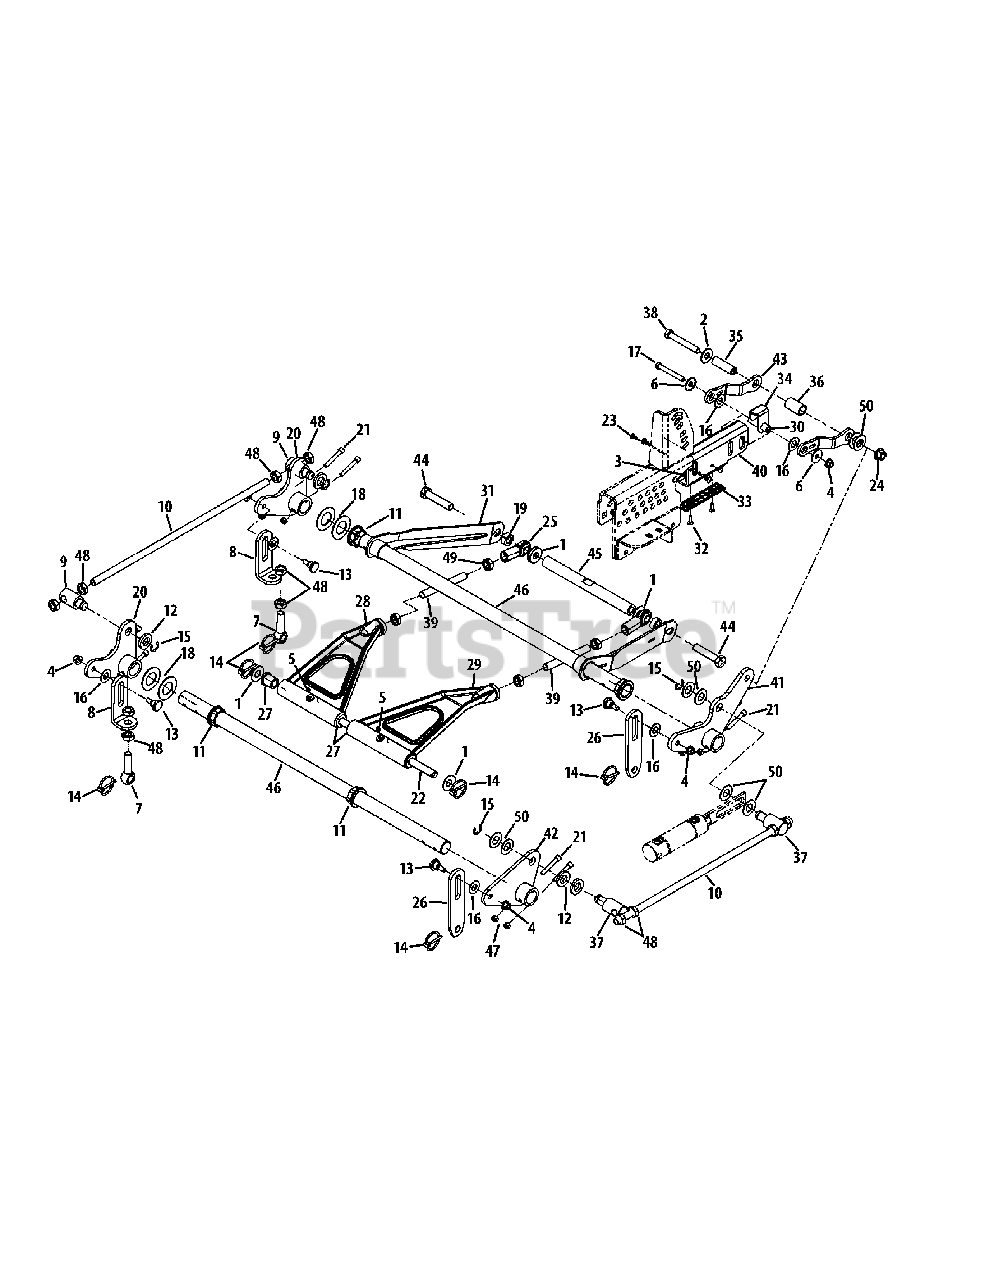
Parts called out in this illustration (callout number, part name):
1	Washer, .655 x 1.5 x .055
2	Washer, .563 x 1.38 x .109
3	Nut, 1/4-20
4	Flg. Cnter. Lock Nut, 3/8-16 (60" Deck)
5	Grease Fitting, 1/4-28
6	Washer, .411 x 1.25 x 1.00
7	Eye Bolt, 5/8-16 x 2.63
8	Eye Bolt Link, 5/8
9	Lift Ferrule
10	Lift Connecting Rod
11	Hex Flange Bearing
12	Spacer, .812 x 1.47 x .218
13	Shoulder Bolt, 3/8-16 x .625 x .437
14	Lynch Pin, 3/16 x 1.25
15	Retainer Clip
16	Washer
17	Hex Screw, 3/8-16 x 3.00
18	Washer, 1.25 x 2.25 x .075
19	Spacer, .630 x 1.06 x .440
20	Assembly Bellcrank
21	Screw, 5/16-18 x 2.0
22	Deck Lift Link Rod (60" Deck)
22	Deck Lift Link Rod (72" Deck)
23	Rivet, 1/4 x .625
24	Flange Top Lock Nut, 1/2-13
25	RH Rod End, 5/8
26	Deck Lift Link
27	Flange Bearing
28	LH Lift Brace Bearing
29	RH Lift Brace Bearing
30	Spacer, .375 x .625 x 2.20
33	Wear Plate, 1.125 x 5.0
35	Spacer, .510 x .750 x 2.38
36	Spacer, .765 x 1.00 x 1.70
37	Lift Ferrule, 1.938
38	Hex Screw, 1/2-13 x 3.5
39	Rod, 5/8-18 x 5.5 (60" Deck)
39	Rod, 5/8-18 x 3.5 (72" Deck)
40	Tube, 3.0 x 1.5
41	Hydro Assist Bellcrank
42	Lift Bellcrank Assembly
43	Loft Offset Yoke Bracket
44	Hex Screw, 5/8-11 x 3.00
45	Front Lift Link Mount Shaft
46	Deck Lift Shaft
47	Hex Lock Nut, 5/16 -18
48	Jam Nut, 5/8-11
49	Jam Nut, 5/8-18
50	Flat Washer, .76 x 1.49 x .06
